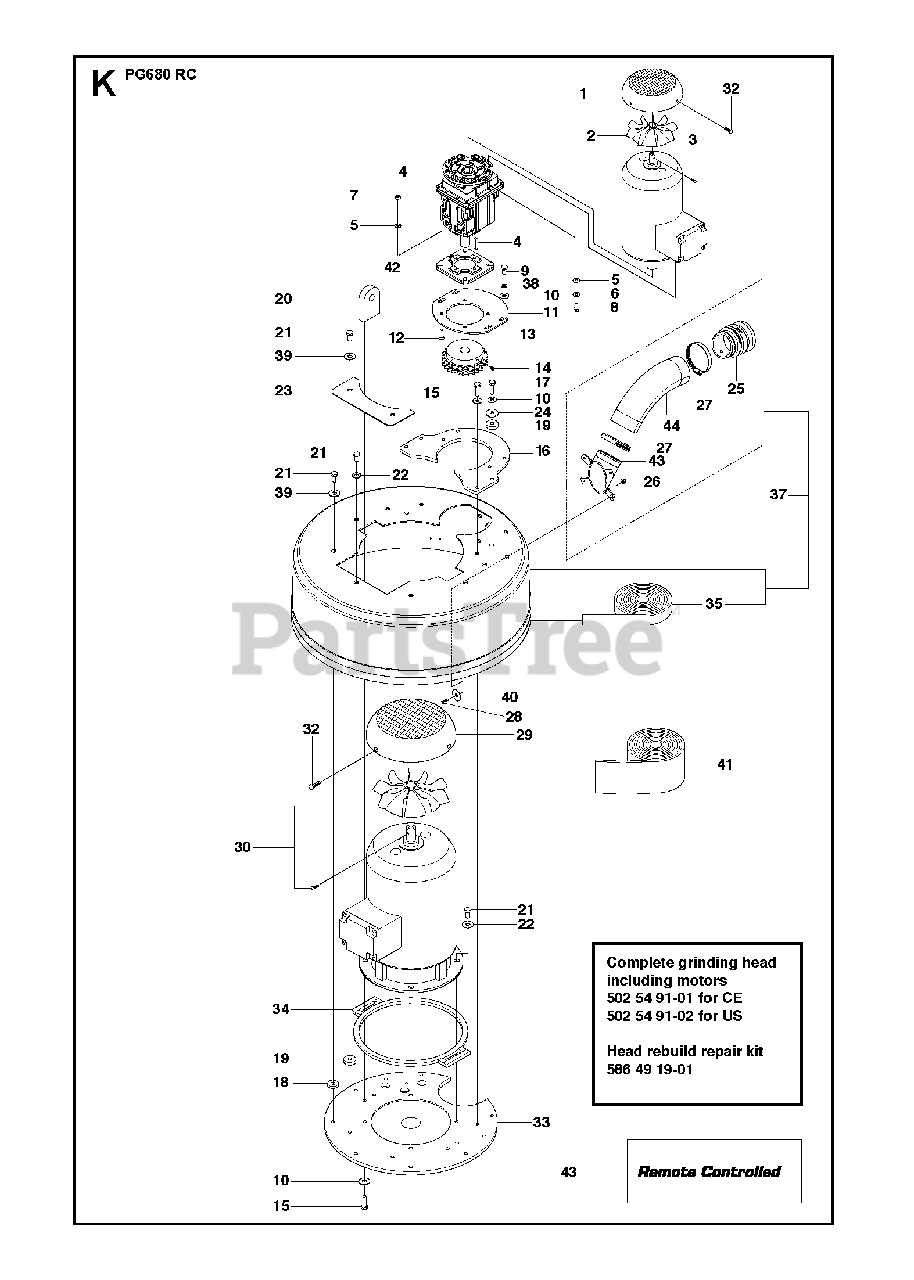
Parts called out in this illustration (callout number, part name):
5	WASHER
6	SPRING WASHER
7	HEXAGON LOCKING NUT
10	WASHER
22	WASHER
26	HEXAGON LOCKING NUT
28	SCREW CRCSFM
